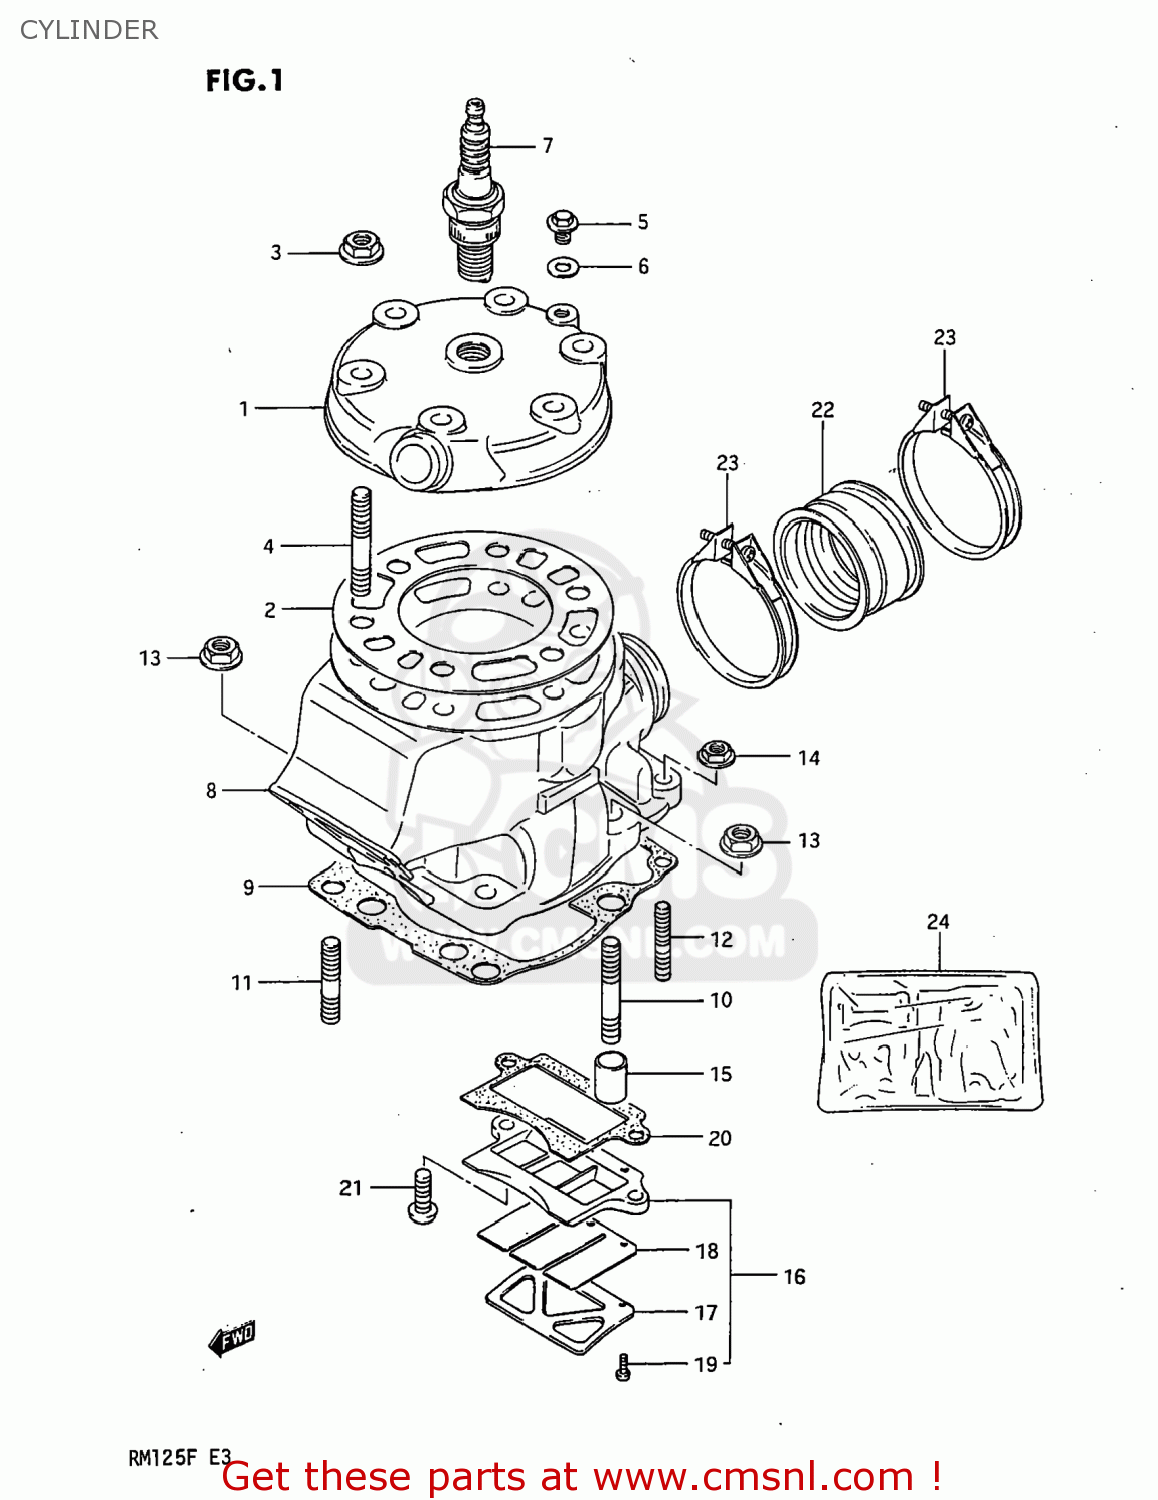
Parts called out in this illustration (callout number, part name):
1	HEAD,CYLINDER
2	GASKET,CYLINDER HEAD (MCA)
3	NUT 8MM
4	BOLT,STUD
5	UNION
6	GASKET(6.2X11X1).2 (NAS)
7	SPARK PLUG
8	CYLINDER
9	GASKET,CYLINDER (MCA)
10	STUD
11	STUD
12	STUD
13	NUT 8MM
14	NUT 6MM
15	PIN
16	VALVE ASSEMBLY,REED
17	STOPPER,REED VALVE
18	VALVE,REED
19	SCREW,REED VALVE
20	GASKET,REED VALVE (MCA)
21	SCREW
22	PIPE,INTAKE
23	CLAMP
24	GASKET (MCA)
